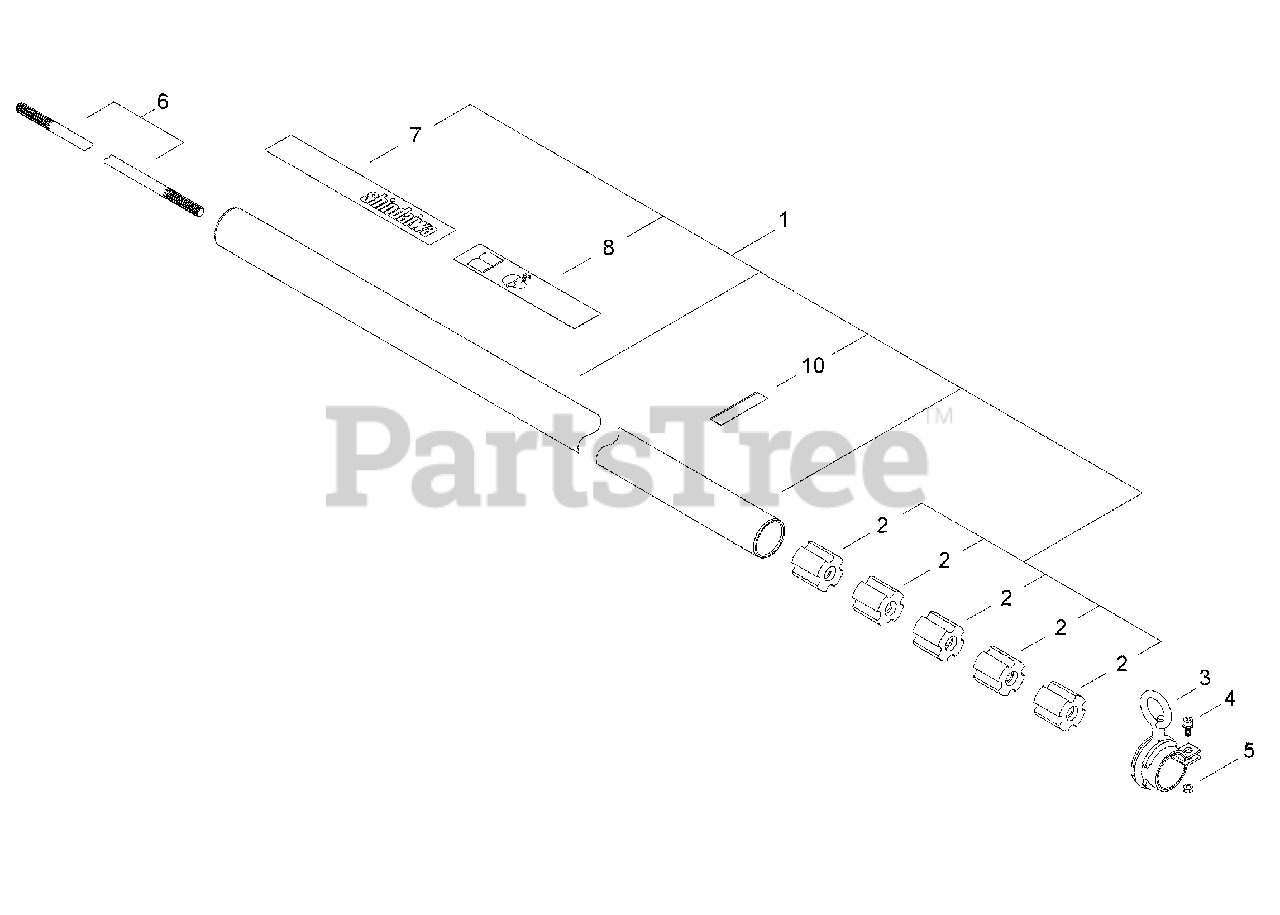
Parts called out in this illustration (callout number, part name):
1	MAIN PIPE ASSY
2	BUSHING
3	HANGER
4	SCREW - 5X12
6	PIPE, MAIN
7	LABEL - TRADE
8	LABEL - CAUTION
10	LABEL - HANDLE LOCATION
